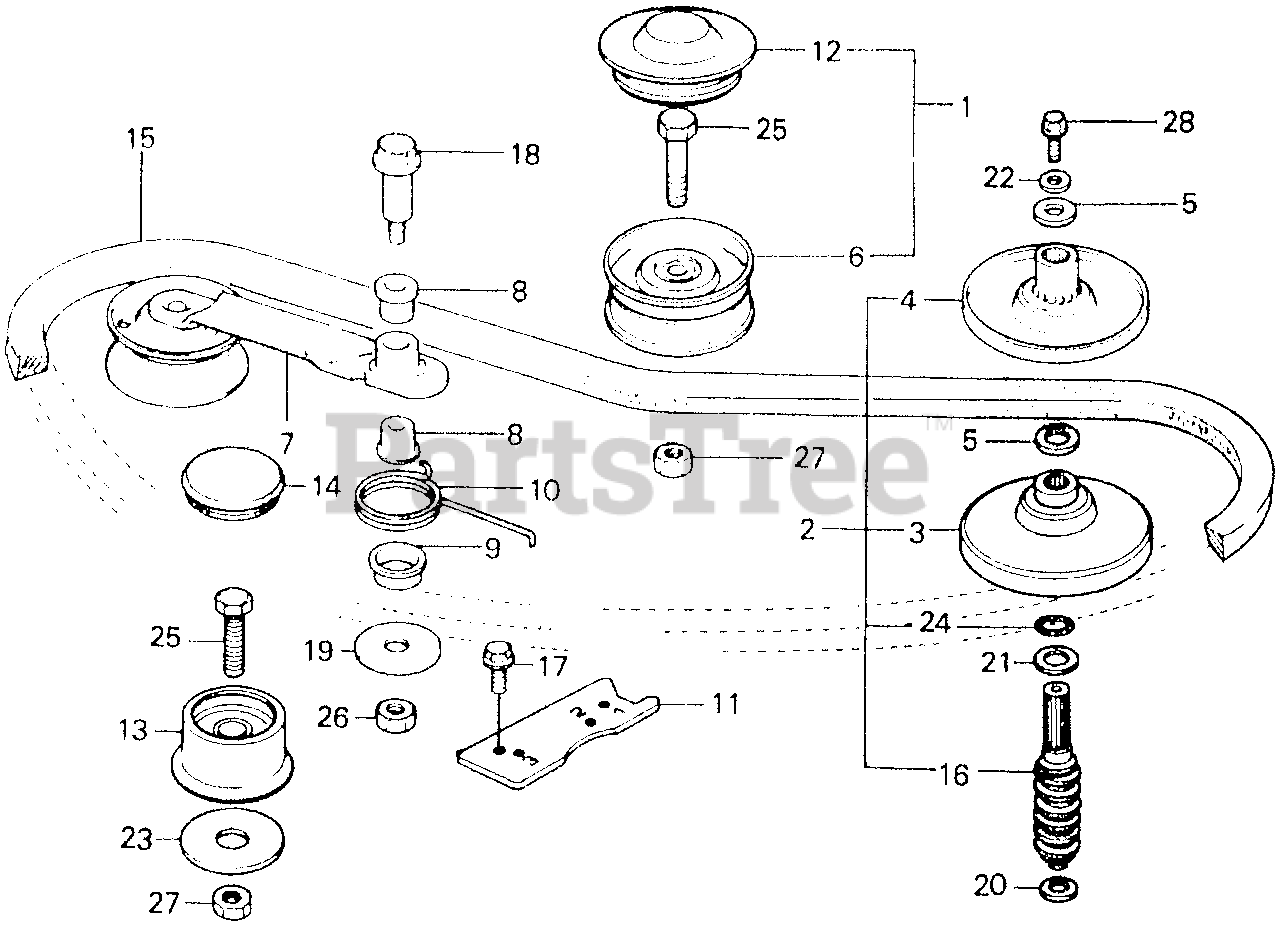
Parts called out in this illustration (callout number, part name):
1	ROLLER
2	PULLEY KIT, DRIVE
3	FACE, DRIVEN
4	FACE, MOVABLE DRIVEN (NOT AVAILABLE)
5	COLLAR, SPEED CONTROL (NOT AVAILABLE)
6	ROLLER
7	ARM, TENSIONER (NOT AVAILABLE)
8	BUSH, TENSIONER ARM (NOT AVAILABLE)
9	BUSH, CHANGE ARM
10	SPRING, TENSIONER ARM
11	PLATE, SPRING HOLDING (NOT AVAILABLE)
12	GROMMET, TENSION ROLLER
13	ROLLER, GUIDE
14	GROMMET, GUIDE ROLLER (NOT AVAILABLE)
15	V-BELT (35)
16	GEAR, DRIVE
17	BOLT, FLANGE (6X12) (CT200)
18	BOLT, TENSIONER ARM
19	WASHER (8MM) (NOT AVAILABLE)
20	WASHER (8MM) (NOT AVAILABLE)
21	WASHER, THRUST (12MM)
22	WASHER (6X17)
23	WASHER (10.5X20.5) (NOT AVAILABLE)
24	O-RING (11.7X1.2) (NOT AVAILABLE)
25	BOLT, HEX. (10X28)
26	NUT, HEX. (8MM)
27	NUT, HEX. (10MM)
28	BOLT, FLANGE (6X12) Use up to Engine SN 1543277.
